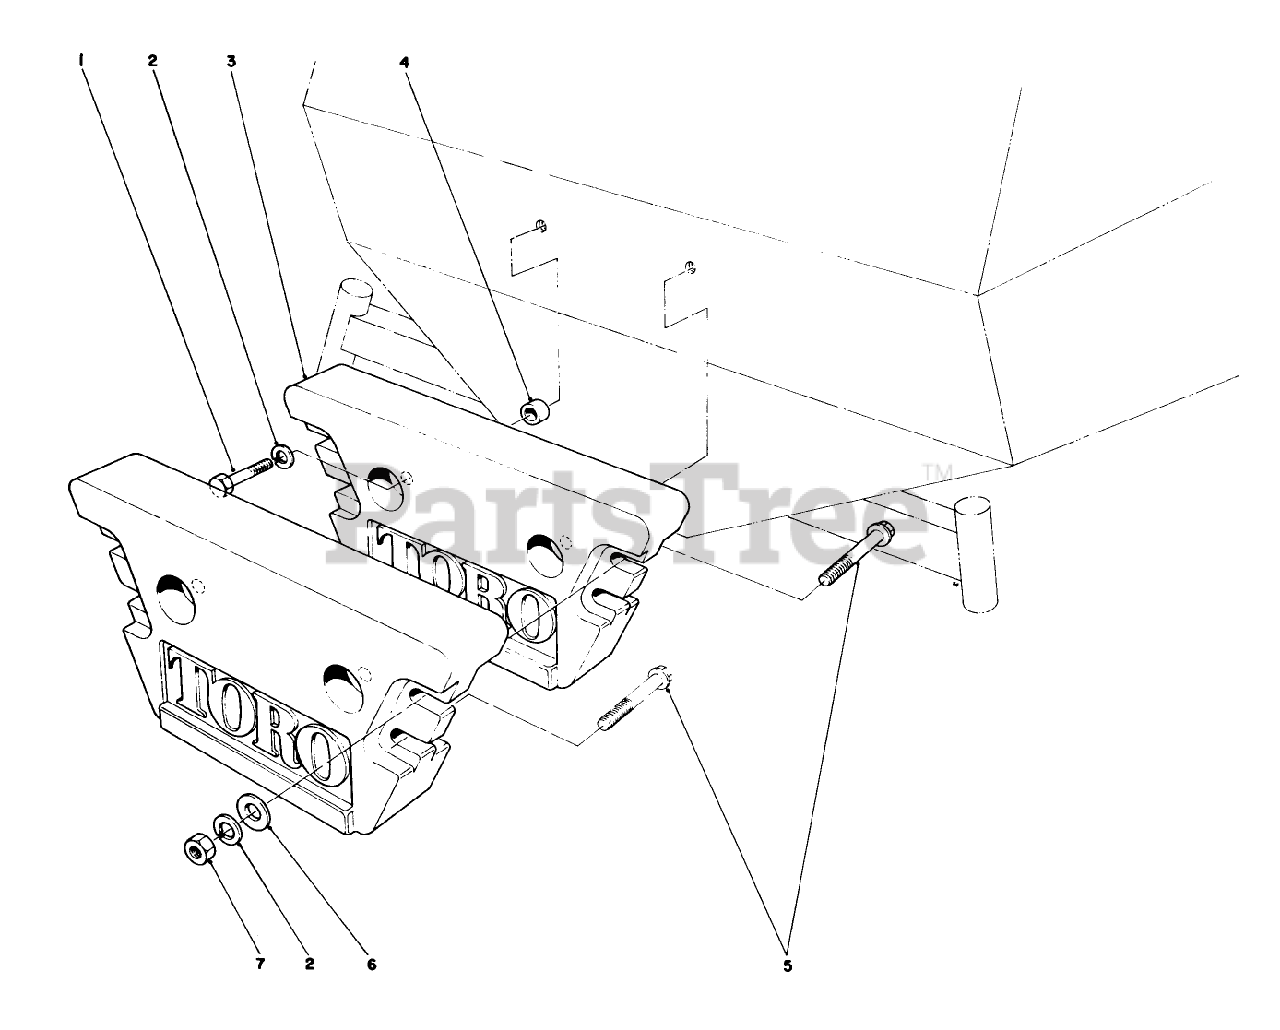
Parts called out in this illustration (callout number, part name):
1	SCREW-HH
2	WASHER-LOCK
3	WEIGHT-REAR
4	SPACER
5	SCREW-HH
6	WASHER-FLAT
7	NUT-HH
